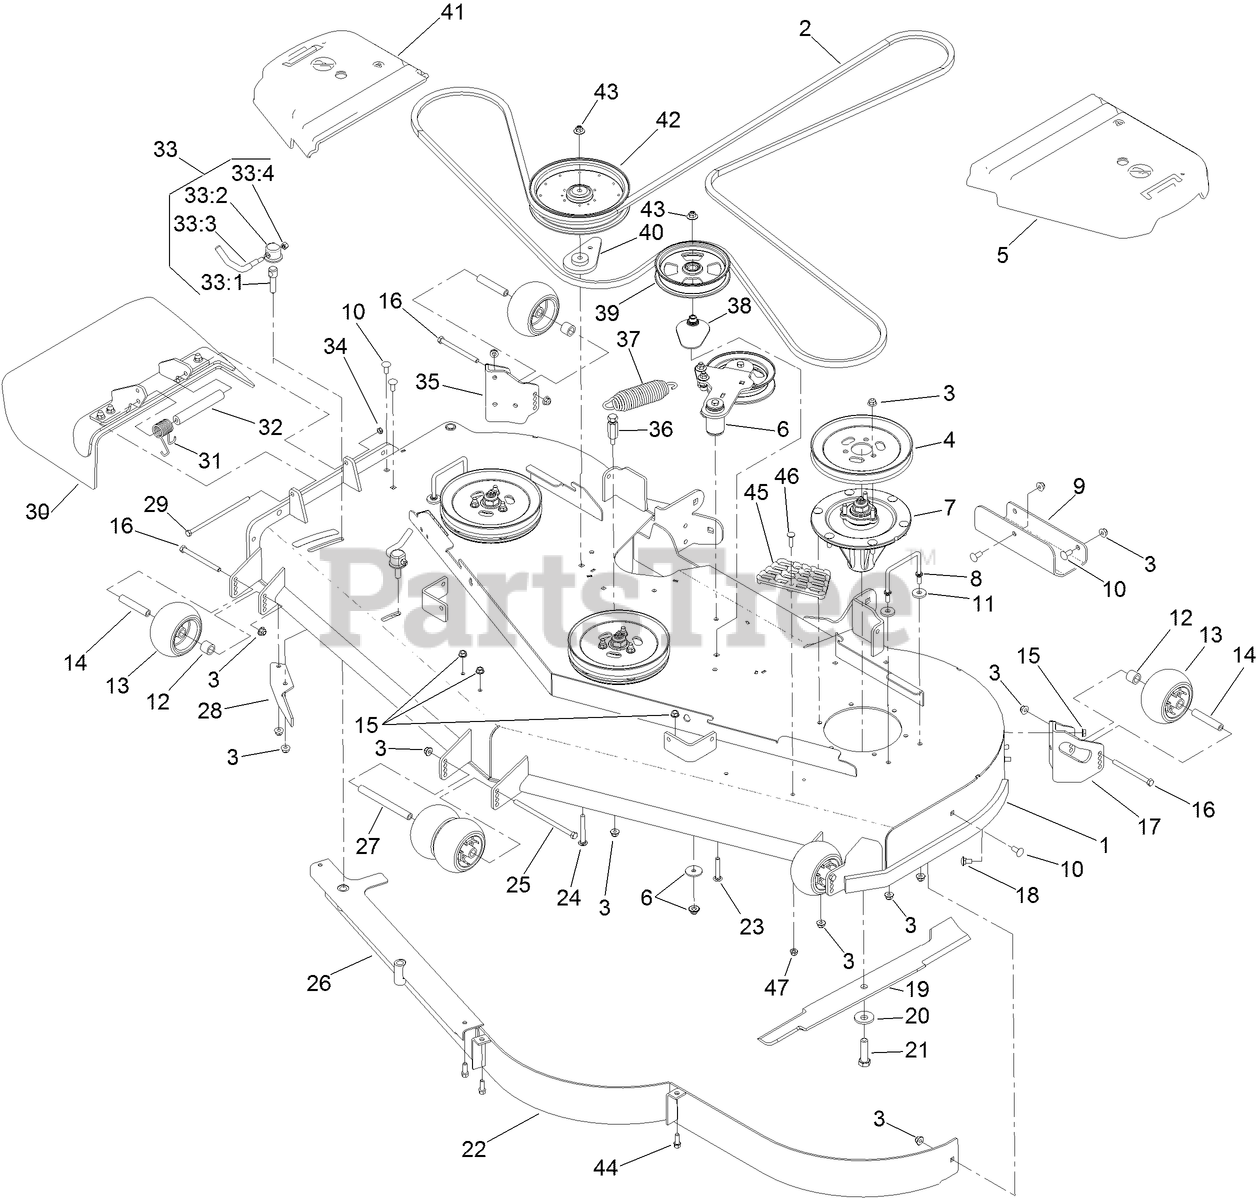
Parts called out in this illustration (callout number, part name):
1	DECK DECAL ASM
2	BELT-V
3	NUT-HF, NI
4	Pulley
5	COVER-BELT, LH
6	IDLER ARM ASM
7	SPINDLE ASM
8	WIREFORM-COVER
9	PLATE-SKID
10	SCREW-CARR
11	WASHER
12	TUBE-SPACER
13	ROLLER-SCALP, ANTI
14	TUBE-SPANNER
15	NUT-HHF, WHIZ
16	SCREW-HH
17	MOUNT-WHEEL, LH
18	SCREW-CARR
19	BLADE-HI FLOW, 24.5 INCH
20	Washer-Blade Bolt, Heavy
21	SCREW-BLADE
23	BOLT-CARR, SHORT NECK
24	SCREW-CARR
25	SCREW-HH
26	BAFFLE ASM
27	SPACER-WHEEL
28	BAFFLE-DISCHARGE
29	SCREW-HH
30	RUBBER DEFLECTOR ASM
31	SPRING-TORSION
32	SPACER
33	LEVER ASM
33:1	Screw-Lock
33:2	CAP-LOCK
33:3	Lever-Lock
33:4	NUT-LOCK, NI
34	NUT-LOCK, NI
35	MOUNT-WHEEL, RH
36	ANCHOR-SPRING, TALL
37	SPRING-EXTENSION
38	SPACER-PULLEY
39	PULLEY-IDLER, FLAT
40	SPACER-IDLER
41	COVER-BELT, RH
42	PULLEY-IDLER
43	NUT-FLANGE, NI
44	SCREW-HWH
45	STEP-DECK
46	SCREW-CARR
47	NUT-HF, NI
